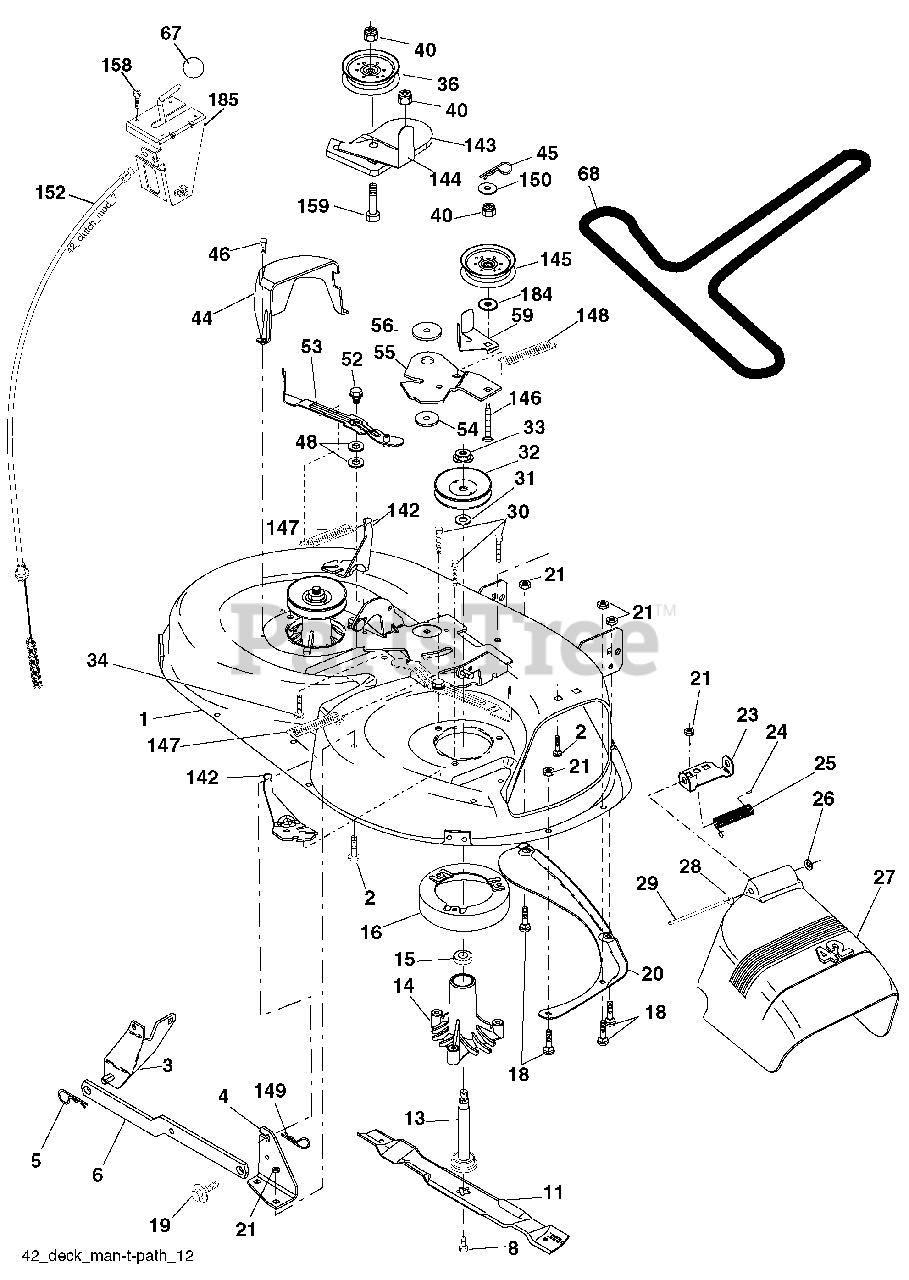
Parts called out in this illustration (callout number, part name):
1	Mower Deck Assembly, 42"
2	Bolt
3	Bracket Asm Fr. Sway Bar 3/42
4	Bracket Asm Deck 42" Sway Bar
5	Retainer Spring
6	Bar Sway Deck
8	Bolt/Washer Asm. 7/16-20 unf (The following Blades are available)
11	Blade Mower 42” Hi-Lift (for bagging and discharging)
11	Blade, Mulching 42” Std (for mulching mowers only)
11	Blade Mulching 42” Premium (For better wear when mulching)
13	Shaft As m. MNDRL
14	Housing, Mandrel, Vented
15	Bearing, Ball, Mandrel
16	Stripper, Mandrel Deck
18	Bolt, Carriage 5/16-18 x 5/8
19	Bolt, Shoulder
20	Baffle, Vortex
21	Nut
23	Bracket, Deflector Mower 42"
24	Cap, Sleeve 80 x 112 Blk Mower
25	Spring, Torsion, Deflector 2 52
26	Nut, Push Phos & Oil
27	Shield, Deflector 42" Blk
28	Washer 11/32 x 5/8 x 16 Ga.
29	Rod, Hinge 42" 6 75 W/G
30	Screw Thdrol
31	Washer, Spacer Mower Vented
32	Pulley, Mandrel
33	Nut, Toplock
34	Bolt Carr SH 3/8-16 x 1-1/2 Gr. 5
36	Pulley, Idler, Flat
40	Nut Lock 3/8-16
44	Guard, Mandrel, LH
45	Retainer
46	Screw, Thdrol 1/4-20 x 5/8 T
48	Washer, Hardened
52	Bolt, Shoulder 5/16-18 unc
53	Arm Assembly, Pad, Brake
54	Washer, Hardened
55	Arm, Idler
56	Spacer, Retainer
59	Guard TUV Idler
67	Knob Round
68	V-Belt, 42" Mower
142	Arm Spring Brake Mower
143	Bracket Arm Idler 42"
144	Keeper Belt 42" Clutch Cable
145	Pulley Idler Flat
146	Bolt Carriage Idler
147	Spring Extension
148	Spring Return Idler
149	Retainer Spring Yellow
150	Washer 9/32 x 3/4 x 10 Ga.
152	Clutch Cable 42"
158	Screw Hex Thd Cut 1/4-20 x 1/2
159	Bolt Rdhd Sqn 3/8-16 unc x 1-3/4
184	Washer 13/32 x 7/8 x 10 Ga.
185	Head Asm Cable Clutch
185	Mandrel Assembly
185	Replacement Mower, Complete
